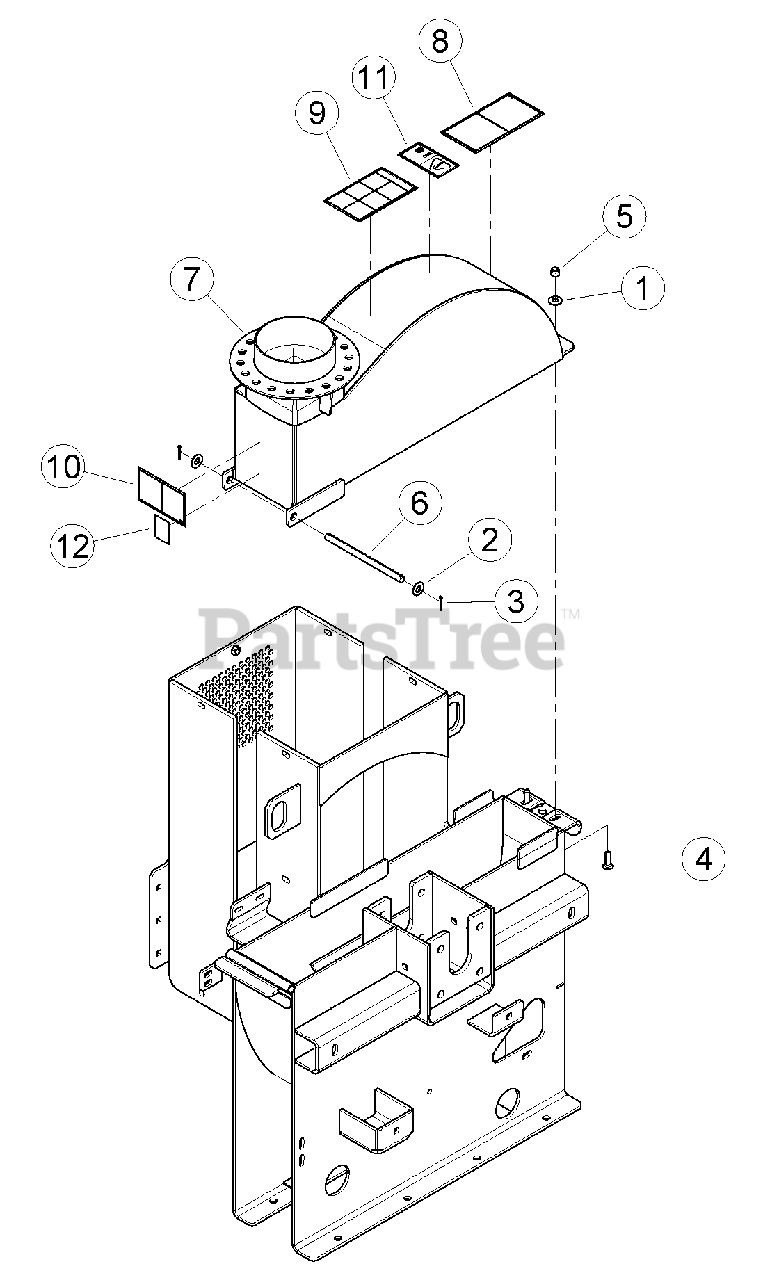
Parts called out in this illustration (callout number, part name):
1	WASHER, 3/8 FLAT ZP
2	WASHER, 1/2 SAE FLAT ZP
3	PIN, 1/8 X 1.00 COTTER ZP
4	BOLT, 3/8 X 1-1/4 CRG GR5 NC ZP
5	NUT, 3/8 NE NYLOCK ZP
6	SHAFT CHIPPER TOP PIVOT
7	ASSEMBLY, CHIPPER HOUSING TOP
8	DECAL, KNIFE ACCESS ISO
9	DECAL, OPERATING INSTRUCTIONS ISO
10	DECAL, DISCHARGE ISO
11	DECAL, MAINTENANCE ISO
12	DECAL, ECHO BEARCAT QR CODE
